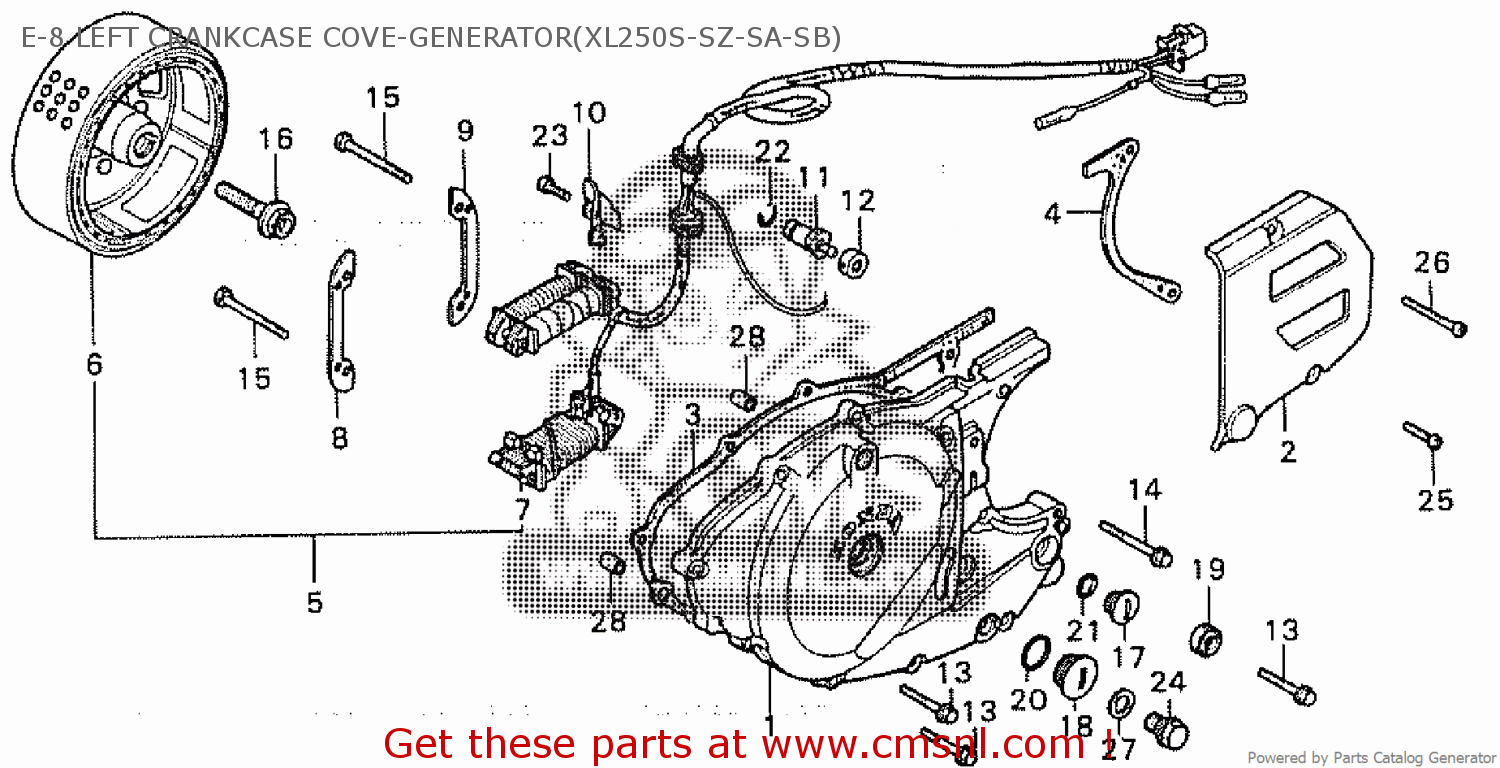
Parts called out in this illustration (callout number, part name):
1	COVER,L.CRANKCASE
2	COVER,L REAR
3	GASKET,L.COVER (MCA)
4	GASKET,L RR COVER (MCA)
5	A C GENERATOR
6	FLYWHEEL COMP
7	STATOR COMP.
8	PLATE A,COIL SET
9	PLATE B,COIL SET
10	CLAMPER,CORD
11	CONTACT ASSY
12	SPACER,NEUTRAL
13	BOLT,FLANGE,6X25
14	BOLT,FLANGE,6X40
15	BOLT,HEX 6X42MM
16	BOLT,FLANGE,12X40
17	CAP,ACG
18	CAP,30MM
19	OIL SEAL,12X25X7
20	O RING, 27X2
21	O-RING,13.8X2.5
22	O-RING 7X1.7
23	BOLT,HEX 6X12
24	BOLT DRAIN 12MM
25	SCREW CROSS 6X18
26	SCREW,CROSS 6X40
